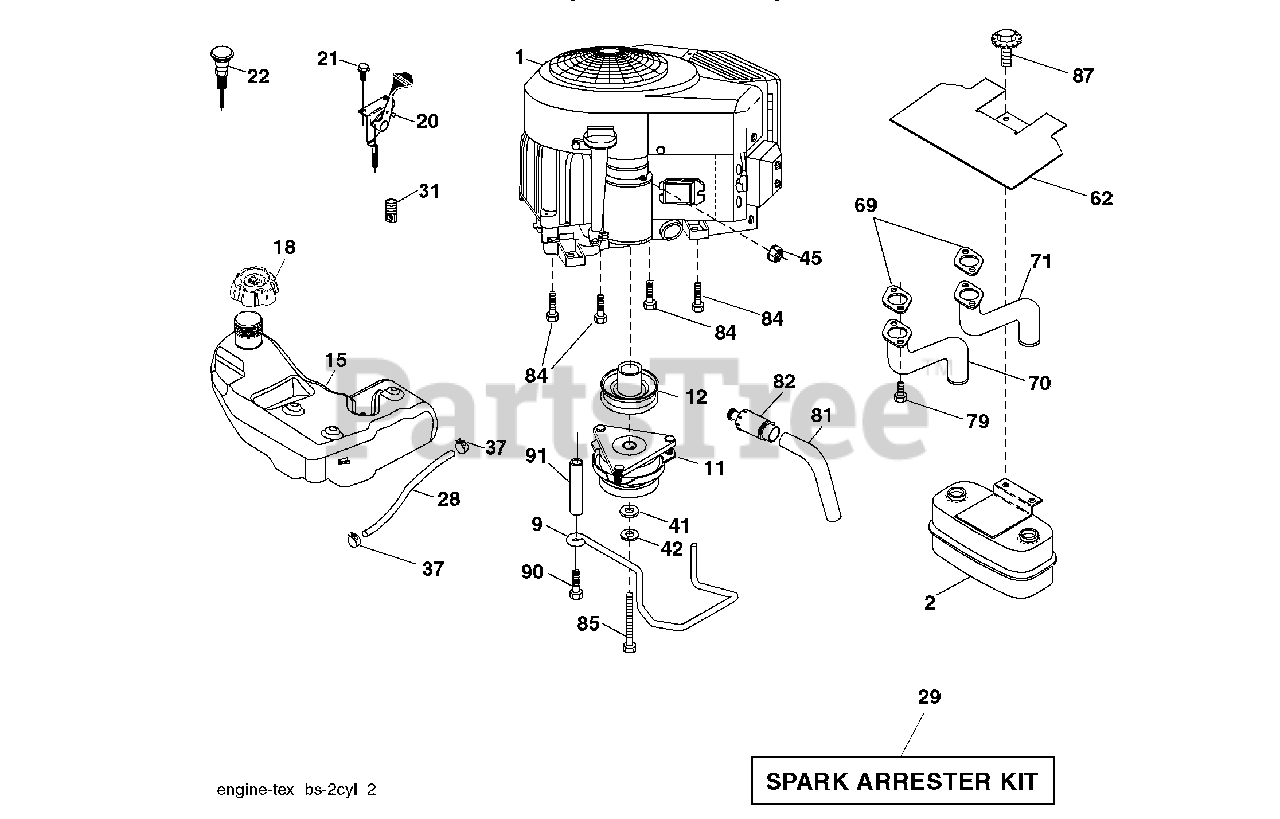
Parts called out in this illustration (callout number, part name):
9	Keeper Asm. Belt Engine
11	Clutch Electric
12	Pulley Engine
15	Tank Fuel 4.0
18	Cap Asm
20	Control Throttle
21	Screw #10 x 0.750 BOS Thread
22	Control Choke
28	Fuel Line
29	Spark Arrester Kit
31	Clip Push-In
37	Clamp Hose
41	Washer 1-1/2 OD x 15/32 ID x .250
42	Washer Lock 7/16
45	Nut Keps Hex 1/4-20 unc
62	Shield Heat Muffler
70	Tube Exhaust LH
71	Tube Exhaust RH
79	Screw Socket HD 5/16-18 x 1
81	Tube Drain Oil Easy
82	Plug Drain Oil Easy
84	Screw 3/8-16 x 1-1/4
85	Bolt 7/16-20 x 3.75 Gr. 5
87	Bolt 5/16-18 unc x 1 w/Sems
90	Screw 3/8-16 x 1
